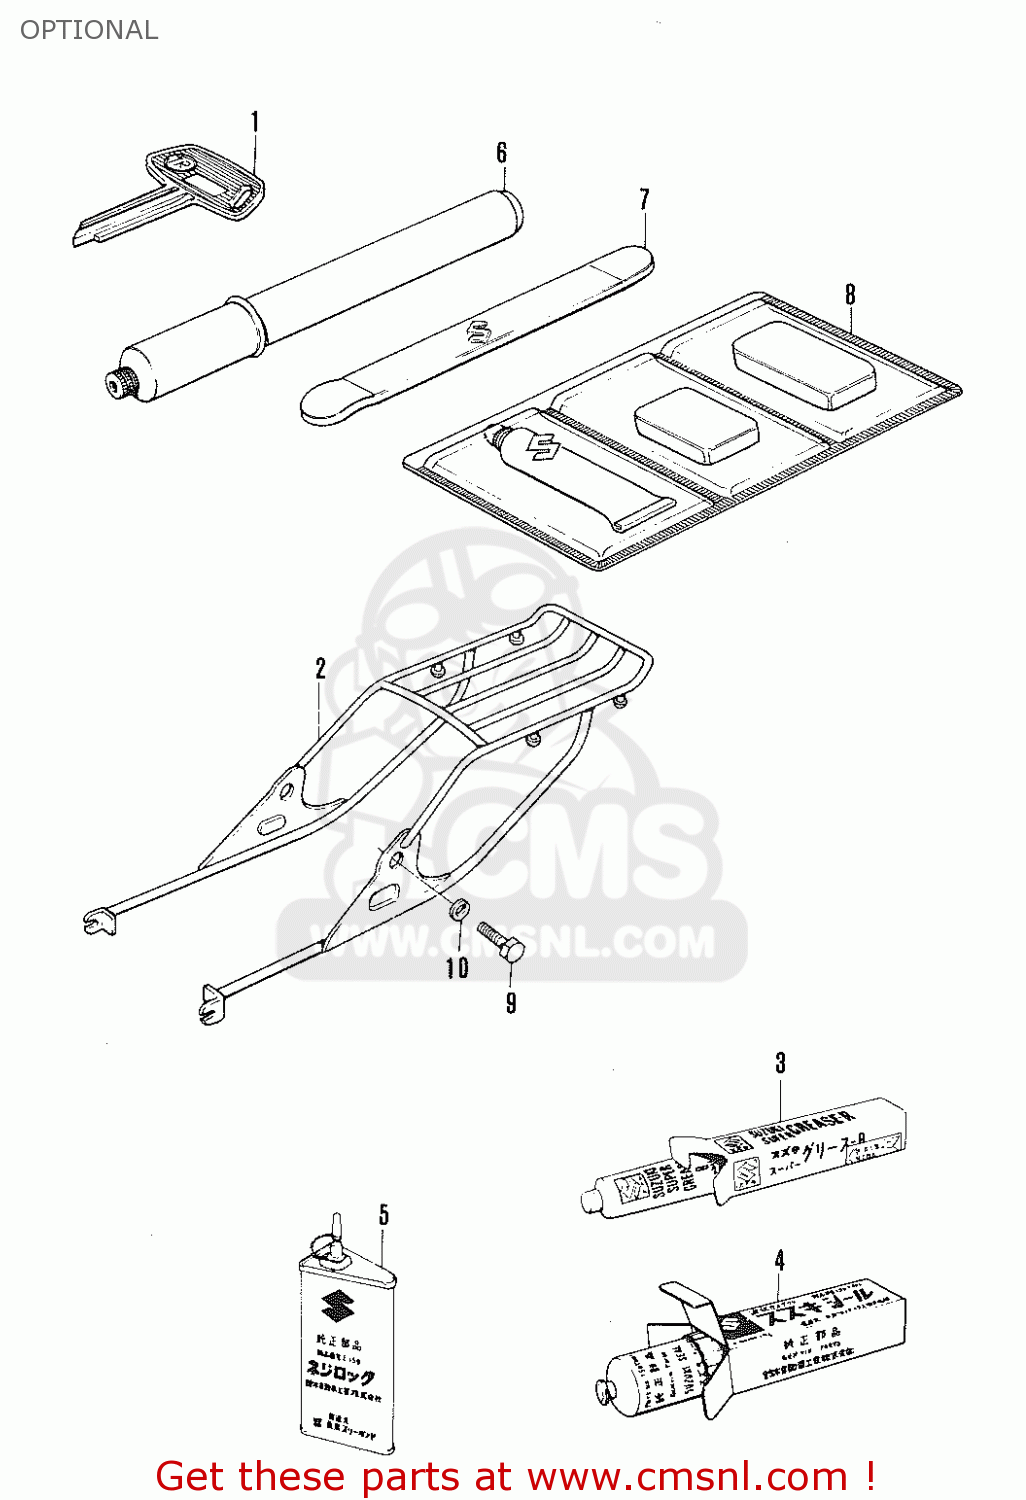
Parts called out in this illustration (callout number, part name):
1	KEY,BLANK
2	CARRIER
3	SUZUKI SUPER GREASE
4	LIQUID GSKT 150G BLACK
5	THREAD CEMENT
6	AIR INFLATOR
7	LEVER,TIRE
8	TUBE REPARING TOOL
9	BOLT
10	LOCK WASHER
